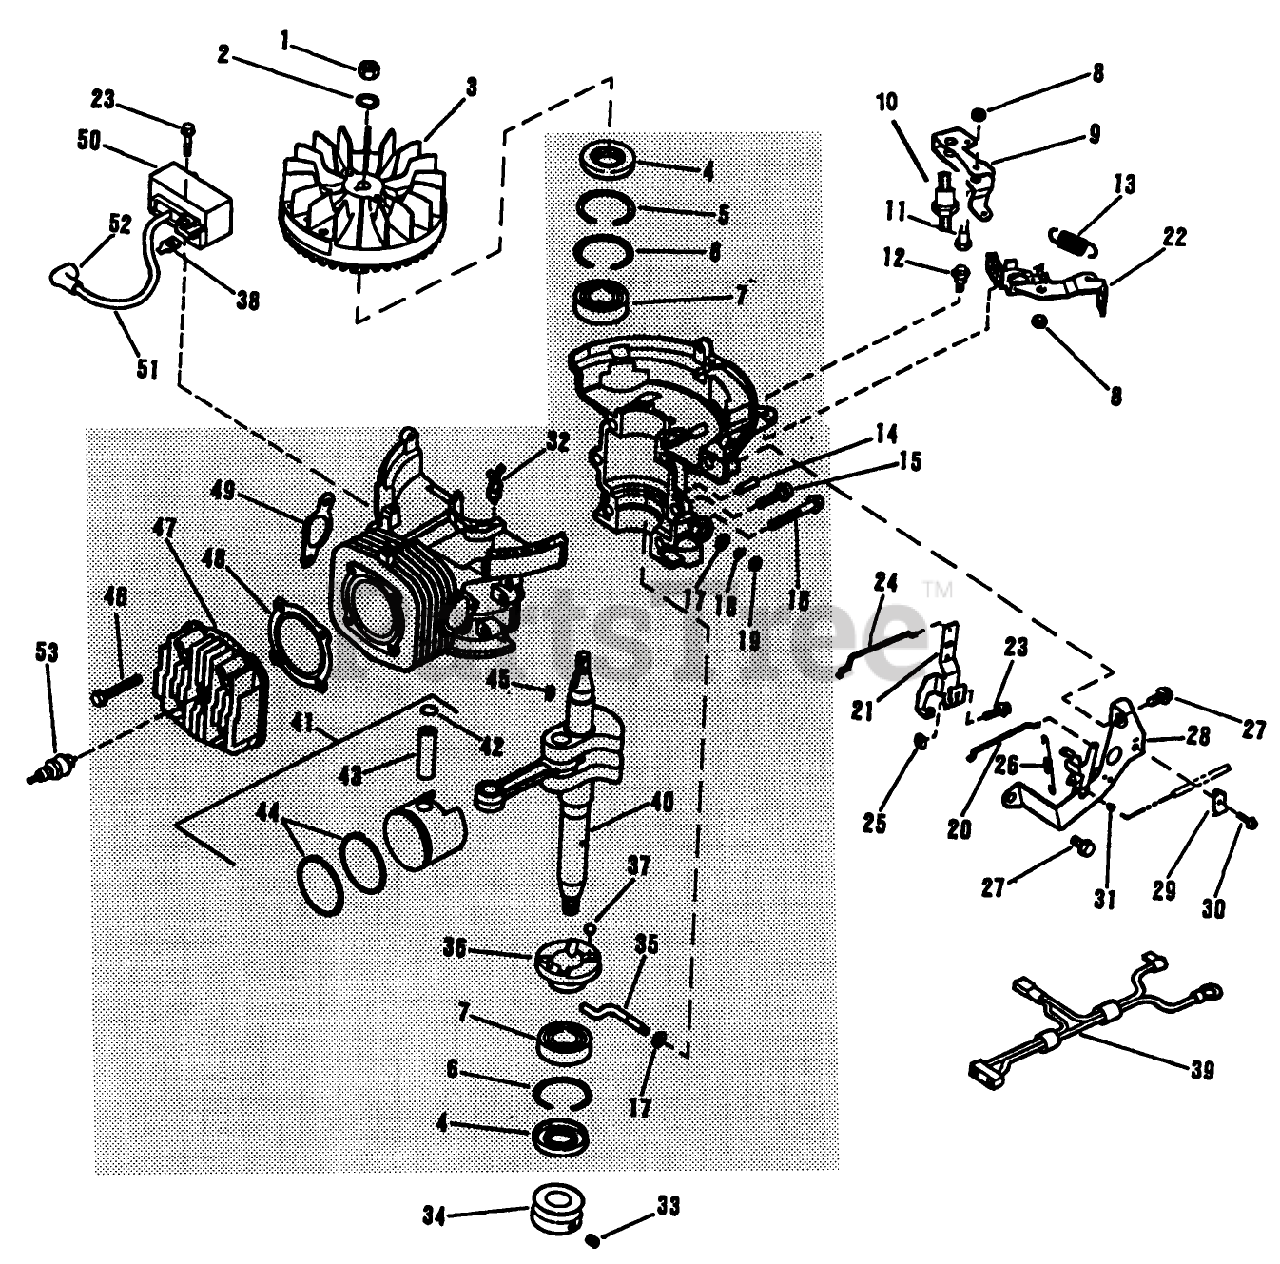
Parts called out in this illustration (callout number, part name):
1	NUT
4	SEAL - OIL SM
5	RING-RETAINER SM
7	BEARING-BALL SM
8	LOCKNUT E
9	ACT.BRAKE LVR. SM
10	STUD-SHOULDER SM
13	SPRING-BRAKE
15	SCREW-H.W.HD. F
16	SCREW-HEX W.H. SM
18	RING-RETAINING
19	SEAL - OIL SM
23	SCREW
24	ROD-THROTTLE SM
26	SPRING-GOV. SM
28	GOVNR BRKT SM
32	WIRE TIE SM
34	PULLEY-ENGINE
44	RING SET S
45	KEY
46	SCREW
47	CYLINDER HEAD SM
49	GASKET - EXH SM
51	HI-TENS.LEAD
53	SPARK PLUG
